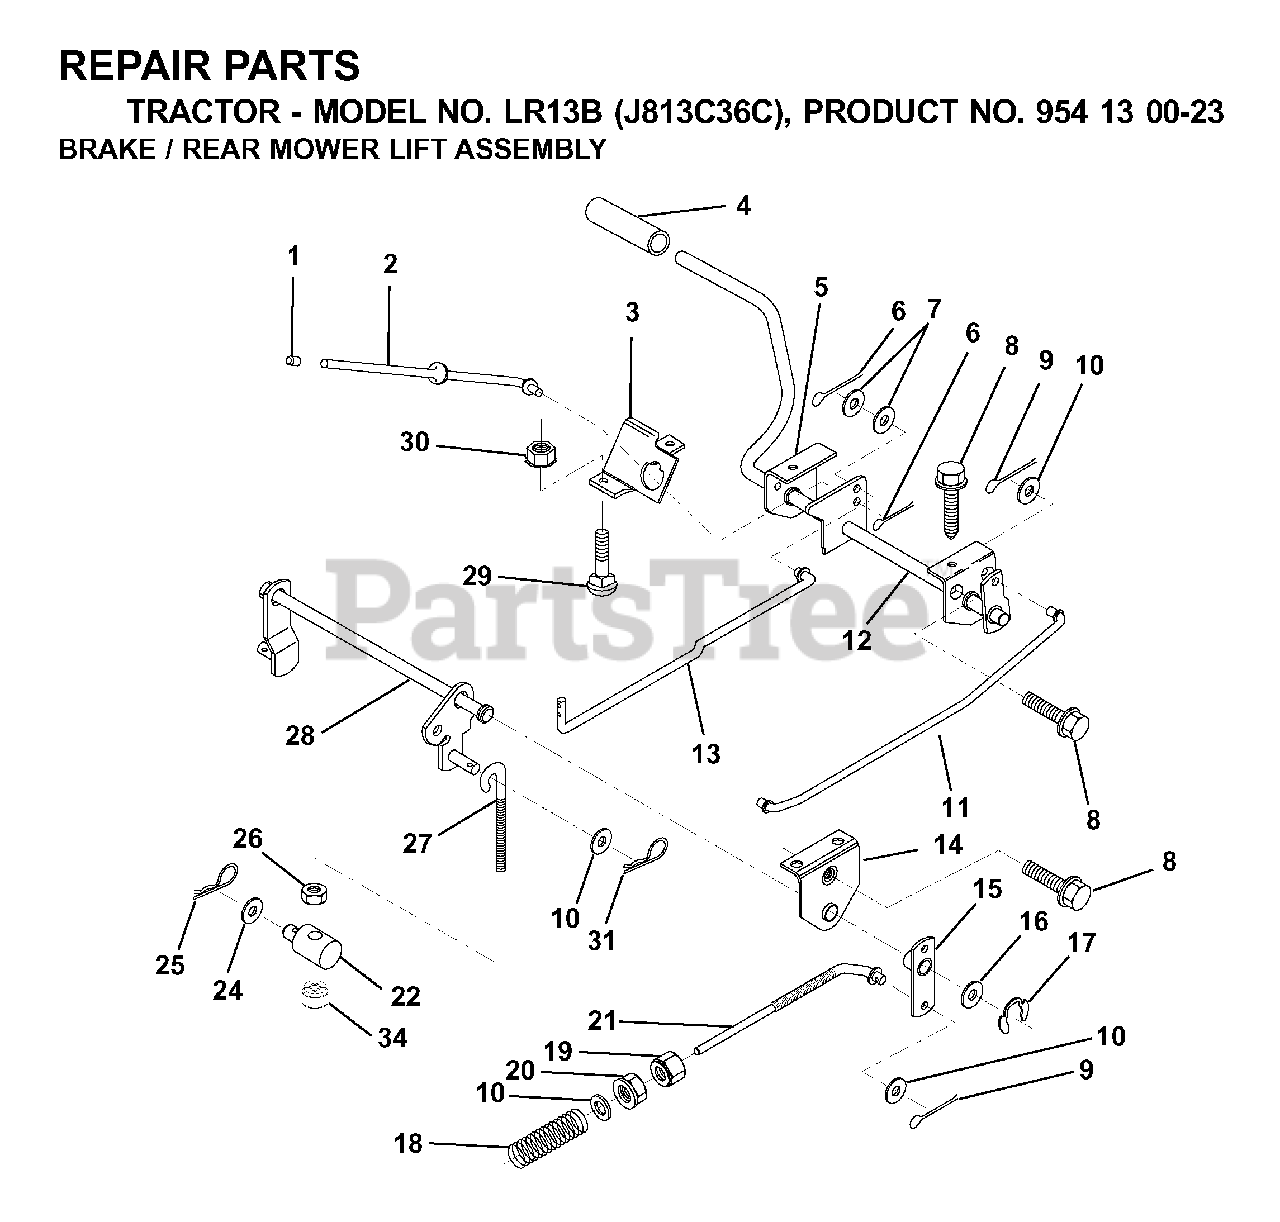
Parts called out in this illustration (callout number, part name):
1	PLUNGER CAP
2	ROD,PARK BRAKE
3	BRKT,PARK BRAKE
4	PEDAL COVER T
5	BRKT,CLU PEDAL LH
6	COTTER PIN
9	COTTER PIN
11	ROD,FRT BRAKE
12	CLUTCH/BRAKE PEDAL ASSY
13	ROD,CLUTCH
14	BRKT,LIFT SHAFT
15	ARM, BRAKE ASMBLY
17	KLIP RING
18	SPRING, BRAKE ROD
19	NUT
20	NUT
21	ROD REAR BRAKE
22	TRUNNION, LEFT
25	SPRING TI
26	LOCKNUT
27	LINK.MOWER.REAR
28	REAR MOWER LIFT ASSY
30	NUT
31	SPRING RETAINER
34	LOCKNUT
